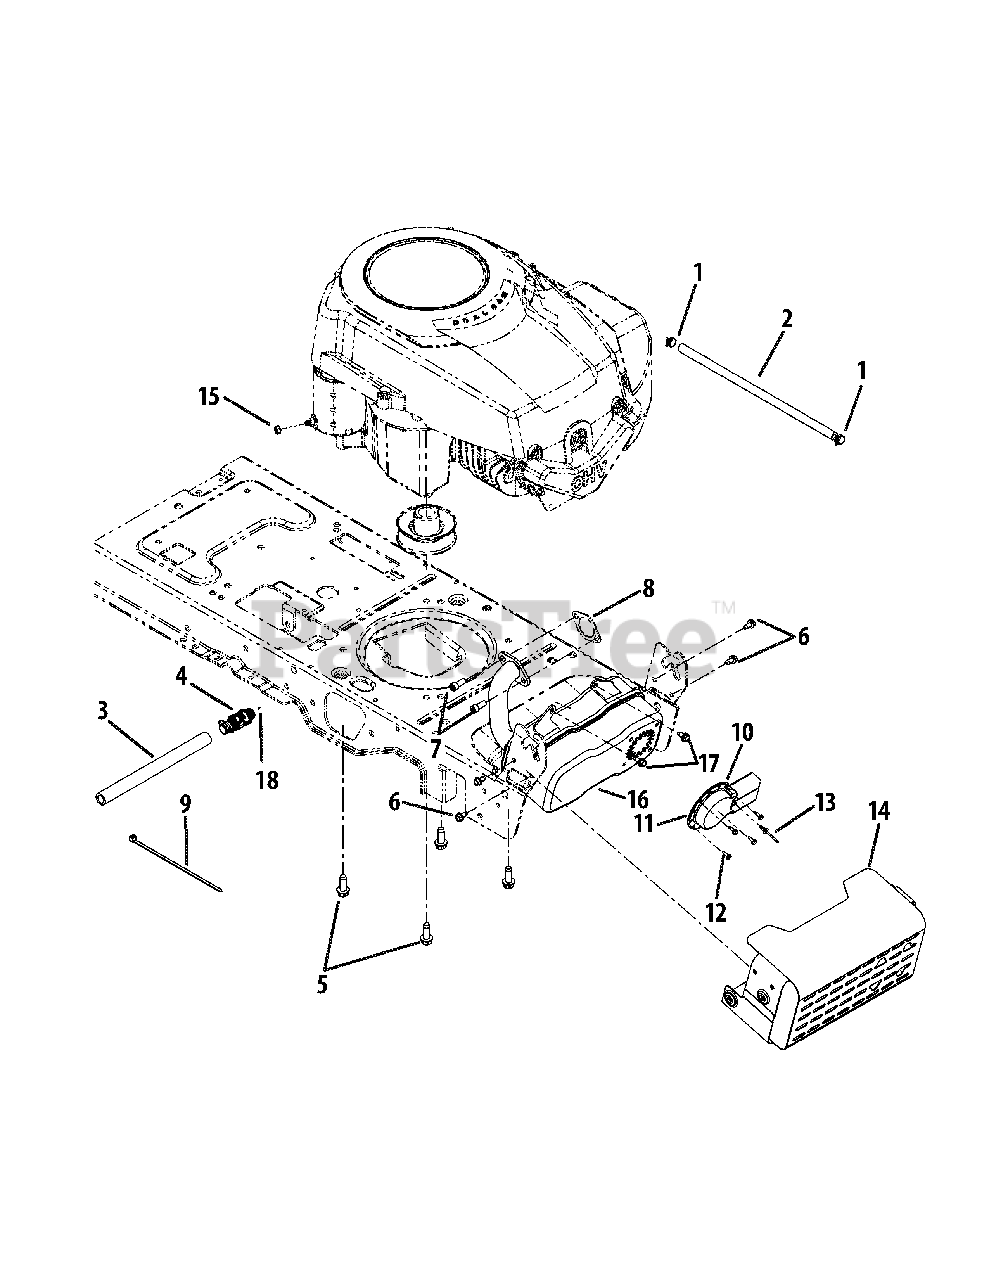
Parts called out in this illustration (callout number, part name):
3	Oil Drain Hose
5	TT Screw 3/8-16 x 1.00
6	Hex Wash S-Tapp Scr 1/4-20 x .50
7	Scr. 5/16-18 x .75
8	Exhaust Gasket
10	Muffler Deflector
11	Long Muffler Deflector
12	Hex AB Scr #8-18 x .50
14	Muffler Shield Assembly
15	Hex Sems Nut 1/4-20
16	Muffler
17	Hex Washer Screw 1/4-20 x .625
